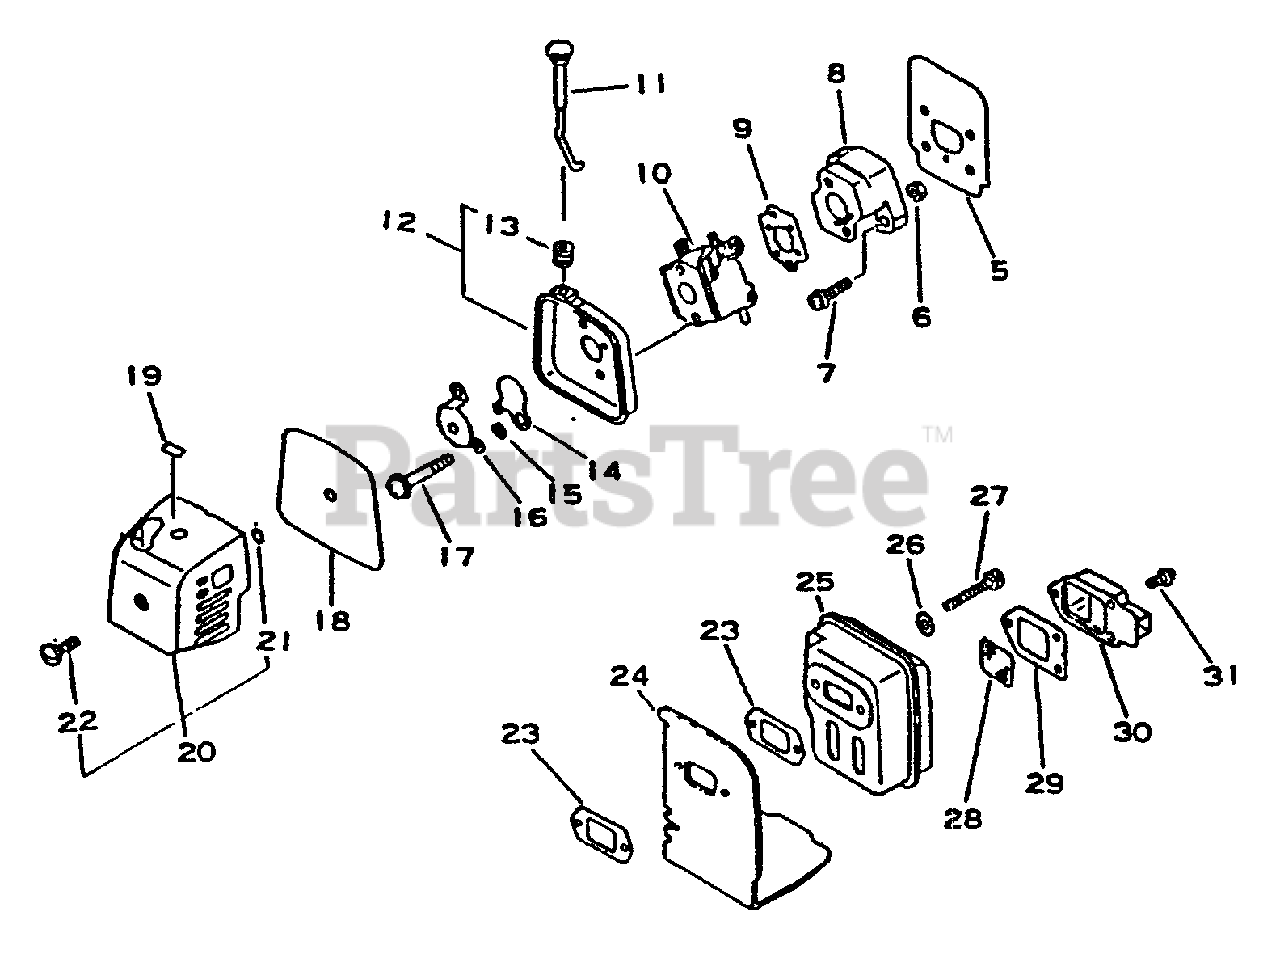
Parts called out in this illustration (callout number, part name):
5	SHIELD, INTAKE
7	SCREW - 5X20
8	INSULATOR, INTAKE
9	GASKET, INTAKE
10	CARBURETOR C1U-K12
11	ROD, CHOKE
12	CASE, AIR FILTER
14	SHUTTER, CHOKE
15	WASHER - 5
16	BRACKET, AIR CLEANER
17	SCREW - 5X57
18	FILTER, AIR
19	LABEL - CHOKE
20	AIR FILTER COVER ASSY
21	O-RING - 4
23	GASKET, EXHAUST
24	COVER, EXHAUST
25	MUFFLER ASSY
26	WASHER - 5
27	SCREW - 5X55
28	SCREEN, SPARK ARRESTOR
29	GASKET, EXHAUST
30	GUIDE, EXHAUST - OUTER
31	SCREW - 4X10
